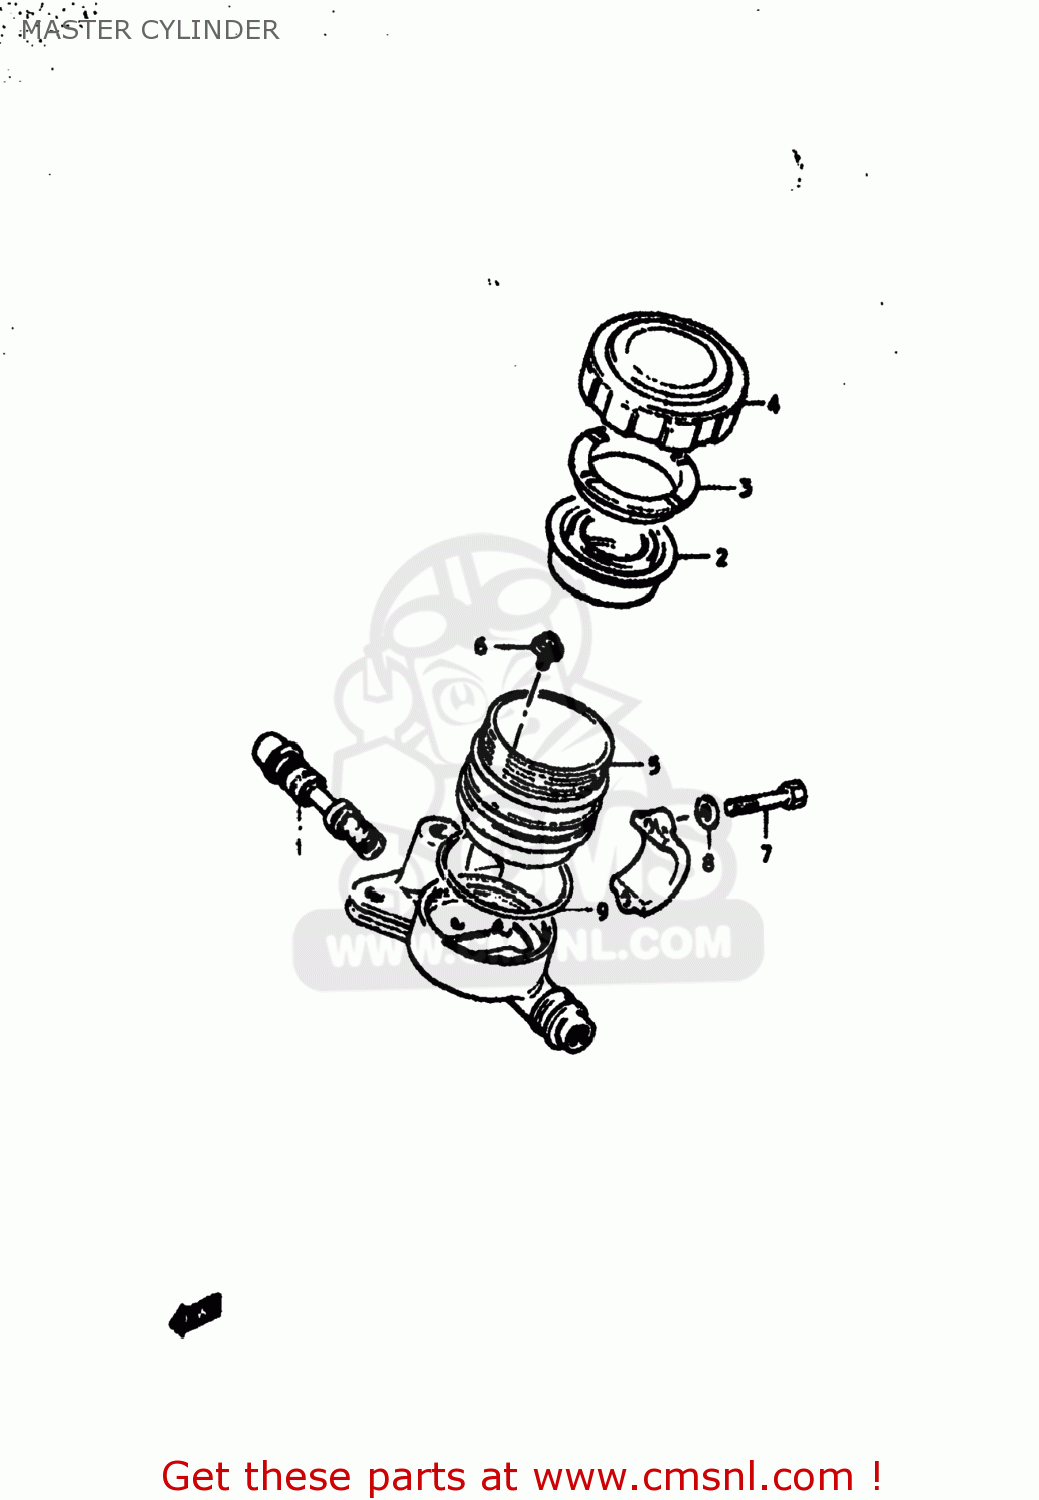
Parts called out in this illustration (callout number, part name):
0	CYLINDER ASSEMBLY,MASTER
1	PISTON & CUP SET
2	DIAPHRAGM
3	PLATE
4	CAP,MASTER CYLINDER,REAR
5	RESERVOIR,MASTER CYLINDER
6	SCREW,MASTER CYLINDER
7	BOLT
8	WASHER
9	O RING
